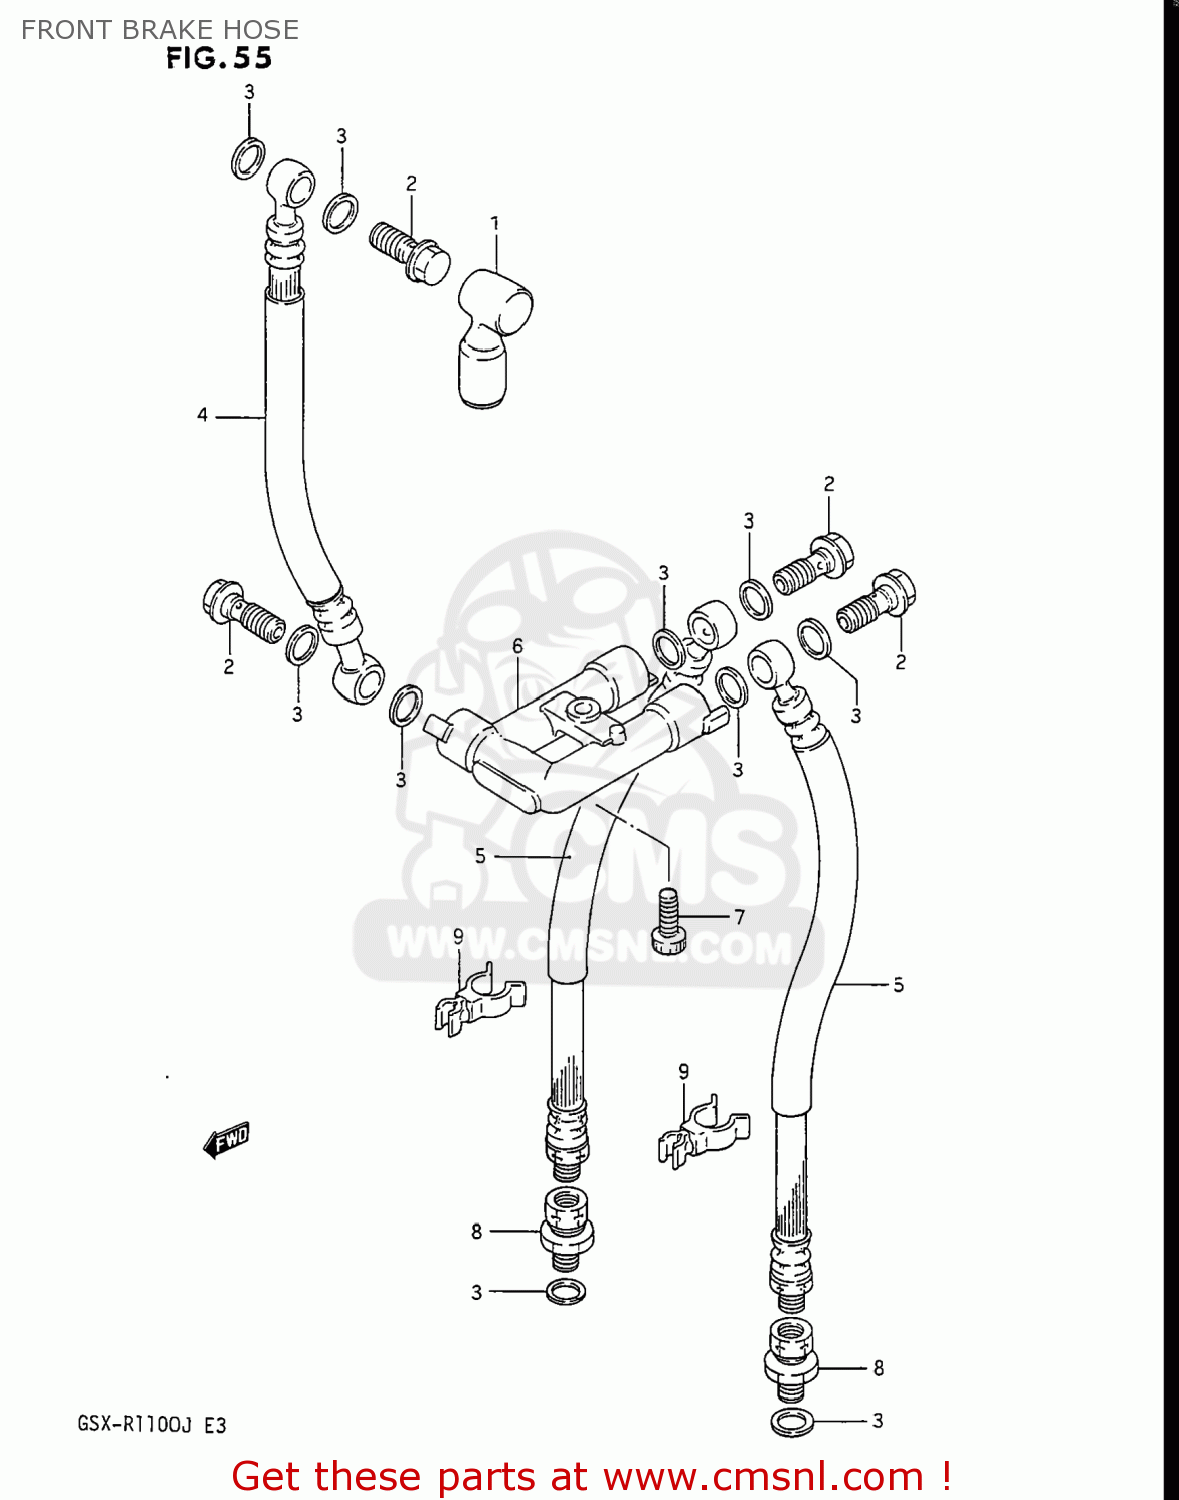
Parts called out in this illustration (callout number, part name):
1	BOOT,MASTER CYLINDER
2	BOLT UNION
3	WASHER(10X15X1.5)
4	HOSE,FRONT BRAKE NO.1
5	HOSE,FRONT BRAKE NO.2
6	JOINT,BRAKE HOSE
7	BOLT
8	ADAPTER,BRAKE HOSE
9	CLAMP
